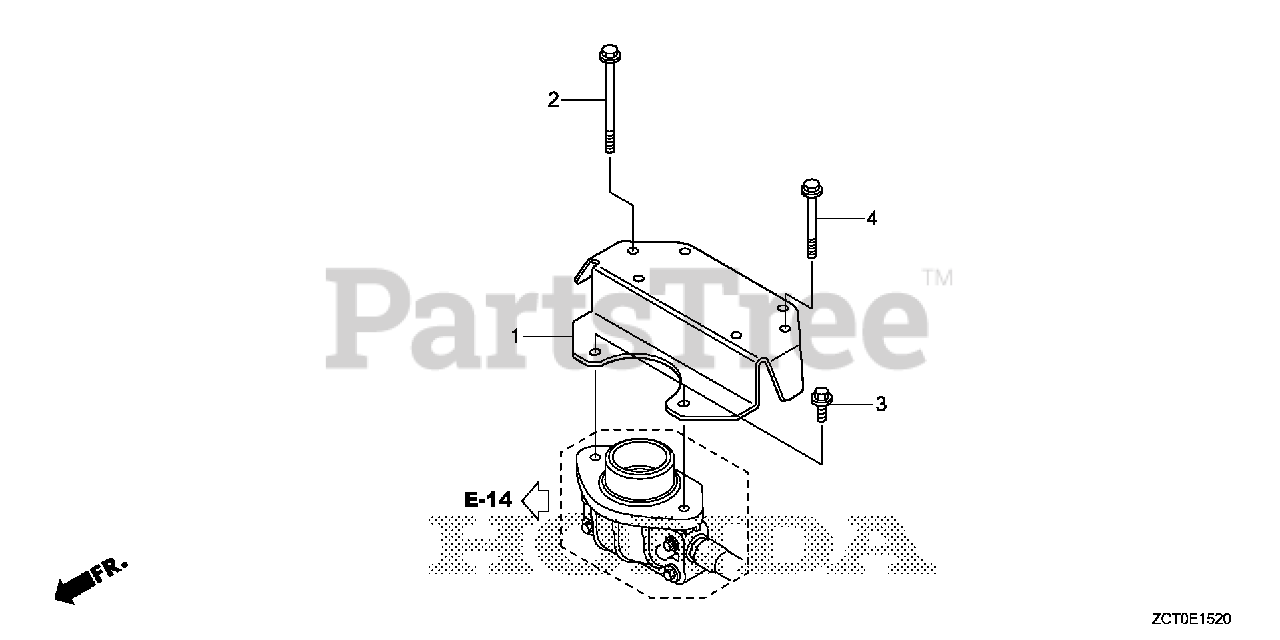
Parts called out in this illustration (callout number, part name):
1	STAY, AIR CLEANER
2	BOLT, FLANGE (6X83)
3	BOLT, FLANGE (6X14)
4	BOLT, FLANGE (6X50)
